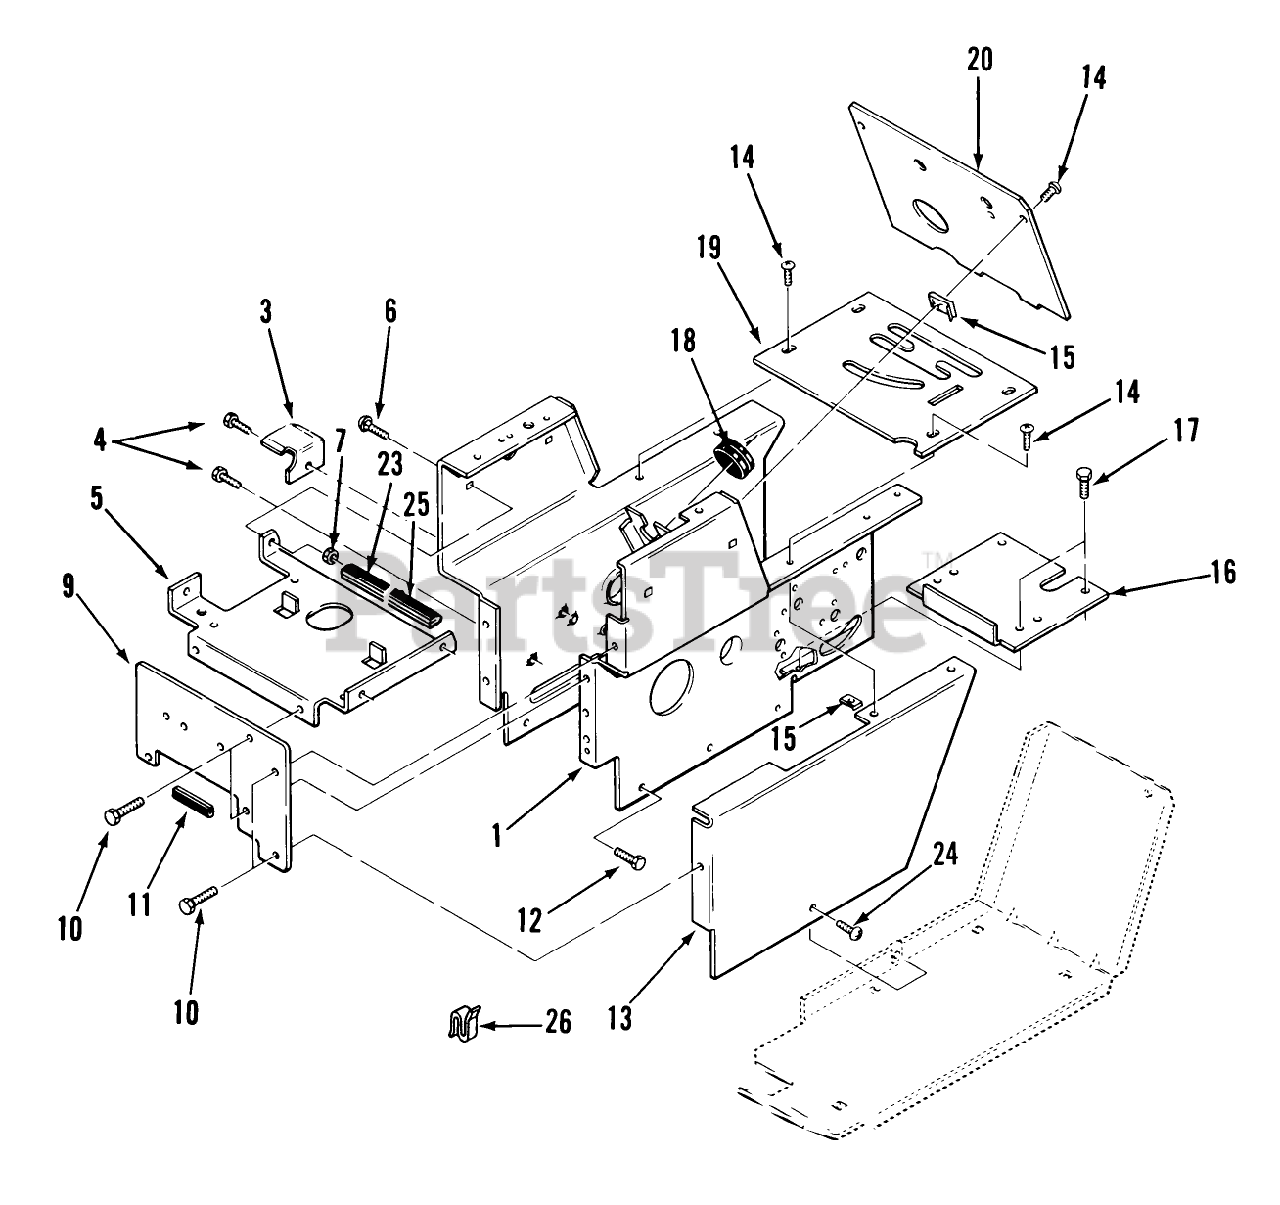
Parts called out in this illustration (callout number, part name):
3	SCREW
9	SCREW
10	GROMMET
16	Carriage Bolt 1/4-20 X 14
25	CARRIAGE BOLT -4
29	Spacer Plate
33	Hairpin Cotter
44	GROMMET
45	Bolt
48	WASHER 5/16 SAE
